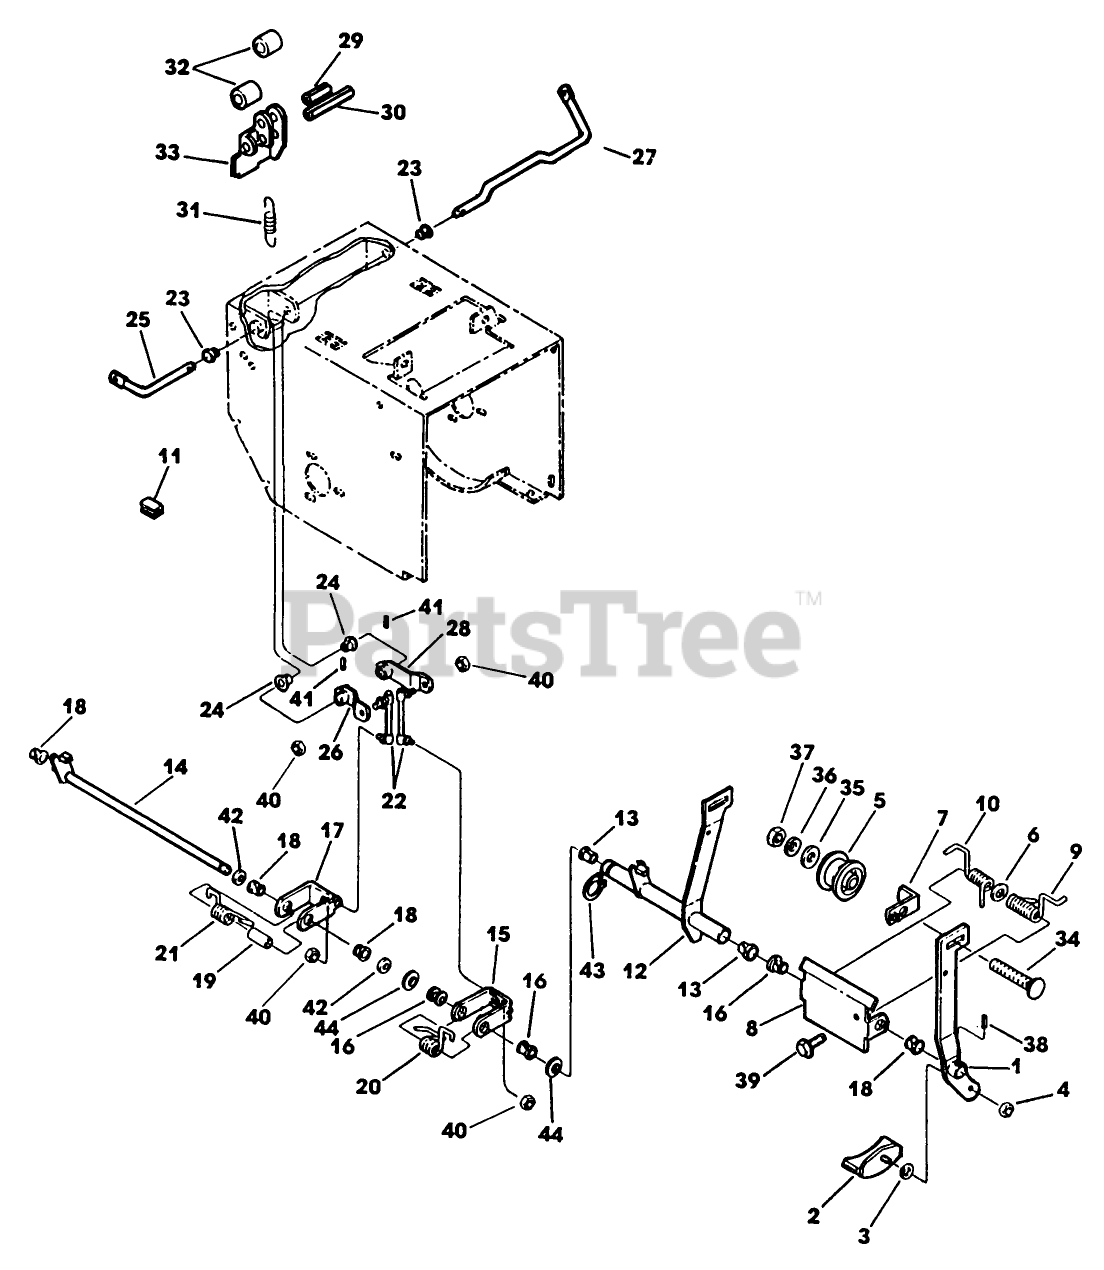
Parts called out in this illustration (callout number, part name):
10	SPRING
27	TRACTION CONTROL ROD
33	INTERLOCK LEVER
35	WASHER
36	WASHER
37	NUT
39	SCREW-HWH
42	WASHER - SHIM
43	RING-RETAINING
